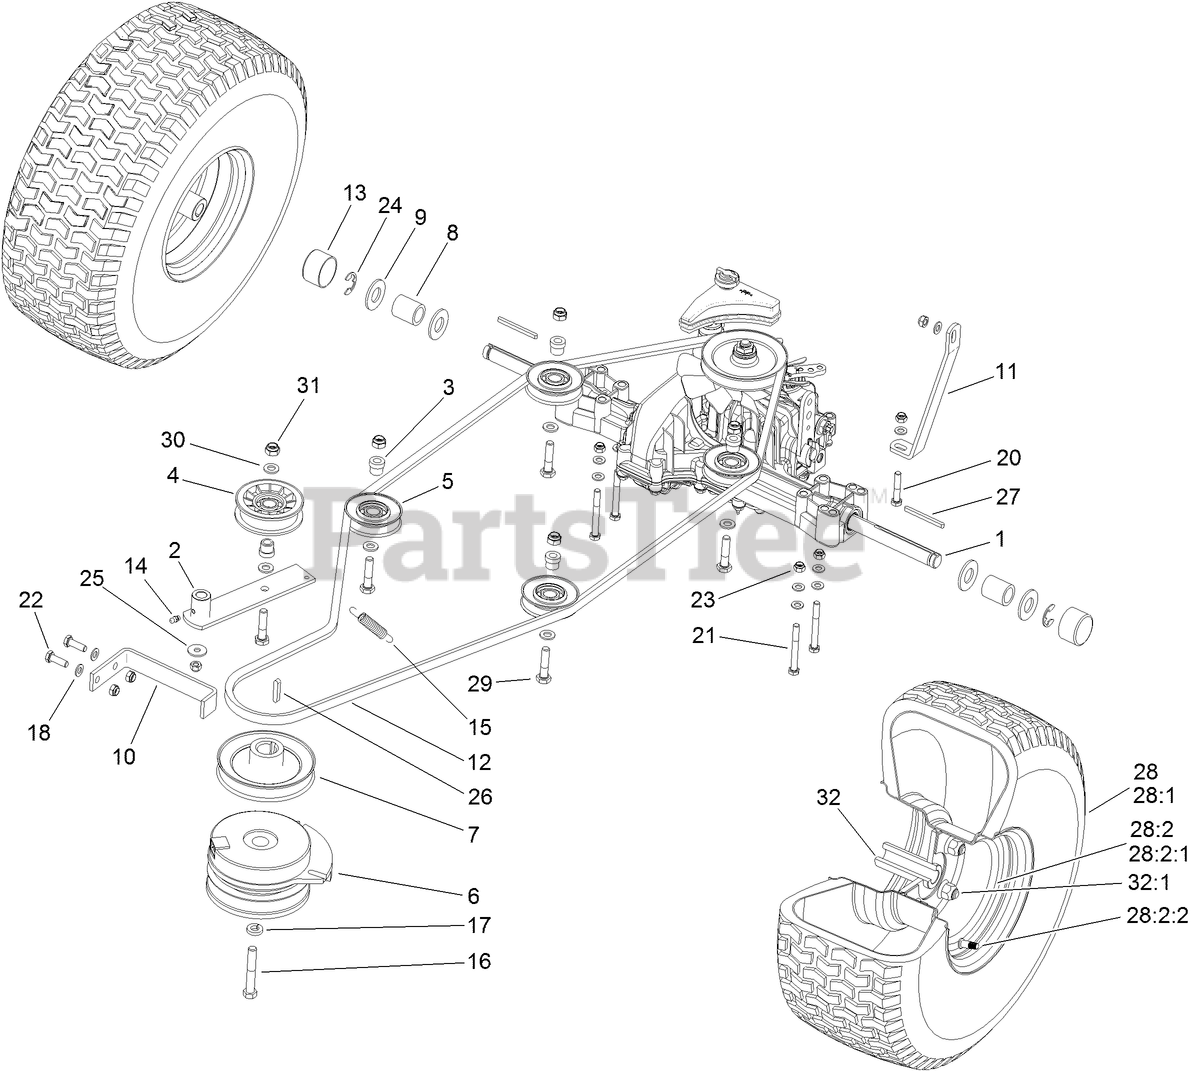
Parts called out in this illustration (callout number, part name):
1	TRANSMISSION
2	ARM-IDLER
3	BUSHING-IDLER
4	PULLEY-IDLER
5	PULLEY-IDLER
6	CLUTCH-ELECTRIC
7	PULLEY-ENGINE
8	SPACER-AXLE
9	WASHER
10	RETAINER
11	STABILIZER
12	V-BELT, TRACTION
13	CAP-HUB
14	FITTING-GREASE
15	SPRING
16	SCREW-HH
17	WASHER-SPRING, BELLEVILLE
18	WASHER-PLAIN
20	SCREW-HH
22	SCREW-HH
23	NUT-LOCK, NI
24	CLIP-SPRING
25	WASHER-PLAIN
26	KEY-SQUARE
27	KEY-SQUARE
28	TIRE AND WHEEL ASM
28:2	WHEEL ASM
28:2:1	Loose Parts Package
28:2:2	Valve-Tire
29	SCREW-HH
30	WASHER-FLAT
31	NUT-LOCK
32	HUB-WHEEL
32:1	NUT-LUG
